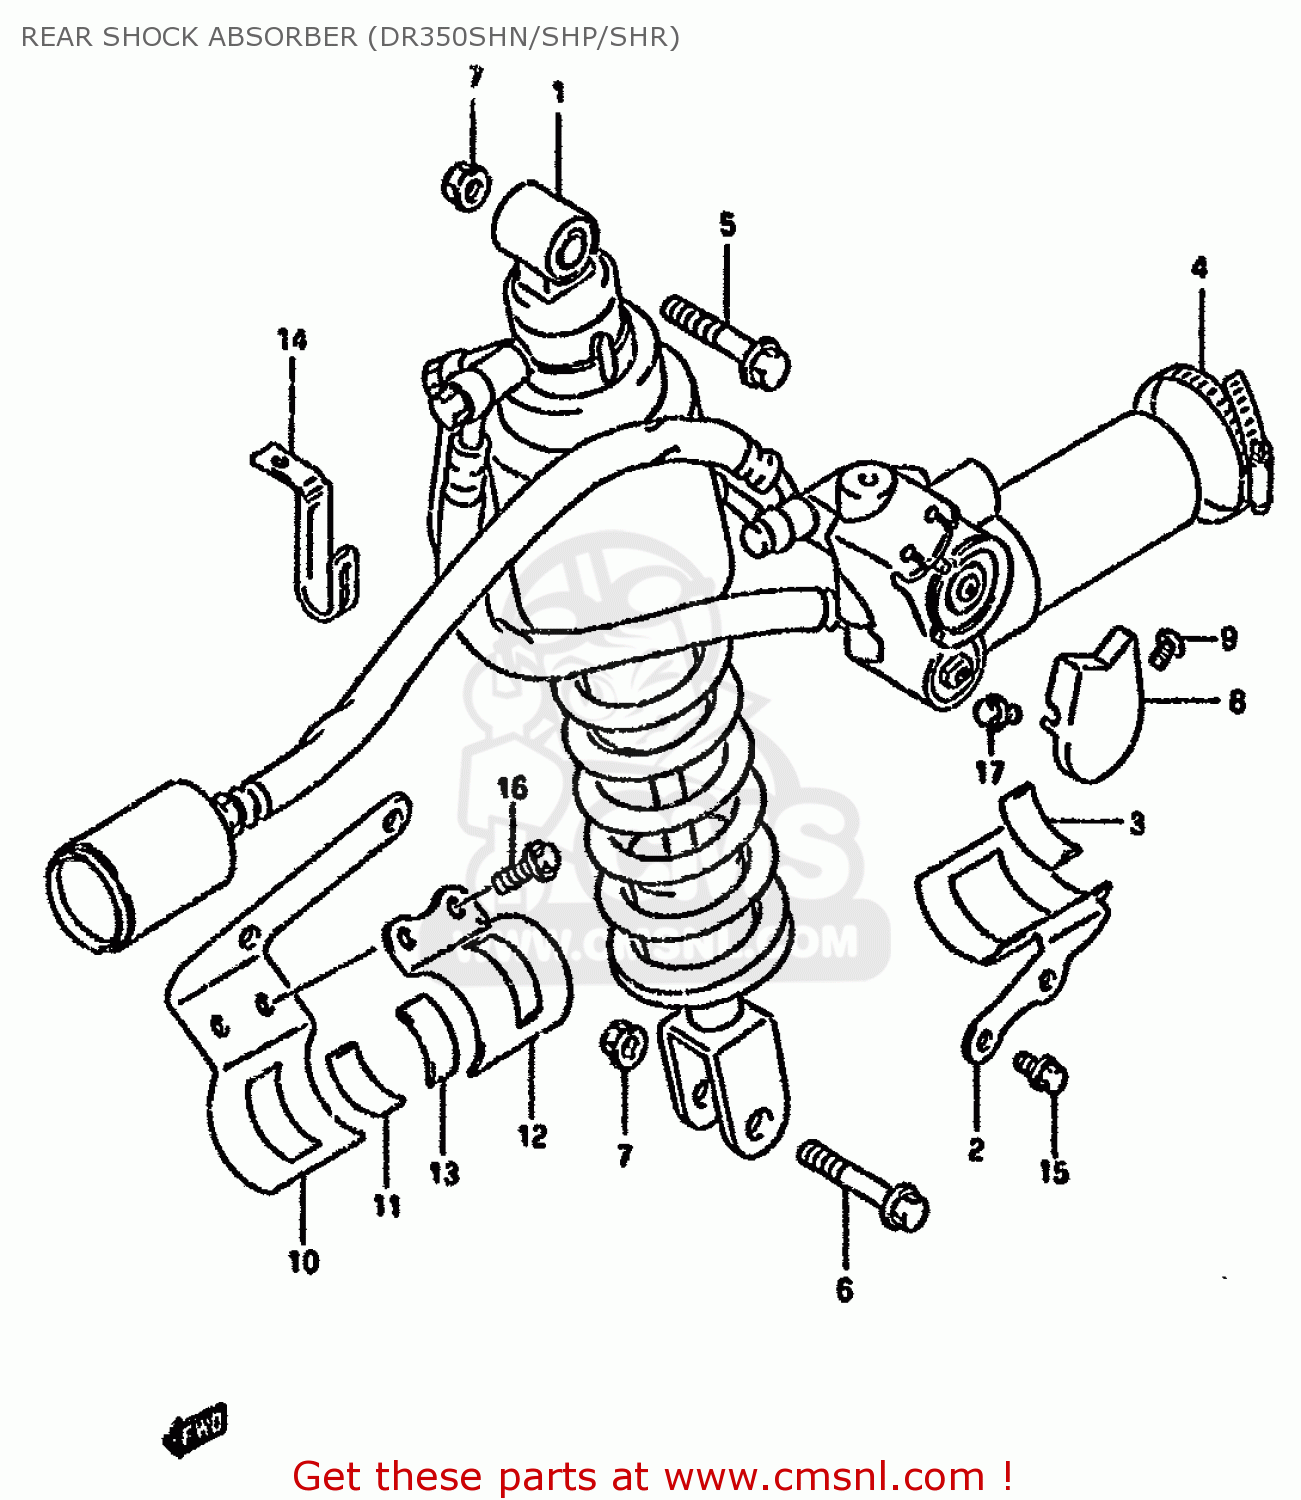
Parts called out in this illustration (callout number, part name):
1	ABSORBER ASSY,REAR SHOCK (WHITE)
2	BRACKET,RESERVER TANK
3	CUSHION,REAR SHOCK ABSORBER
4	CLAMP
5	BOLT,REAR SHOCK ABSORBER
6	BOLT,RR CUSHION ROD UPR
7	NUT
8	COVER,CHAMBER CAP
9	SCREW
10	BRACKET,JOINT NO.1
11	CUSHION,REAR SHOCK ABSORBER
12	BRACKET,JOINT NO.2
13	CUSHION,REAR SHOCK ABSORBER
14	CLAMP
15	BOLT
16	BOLT
17	BOLT
